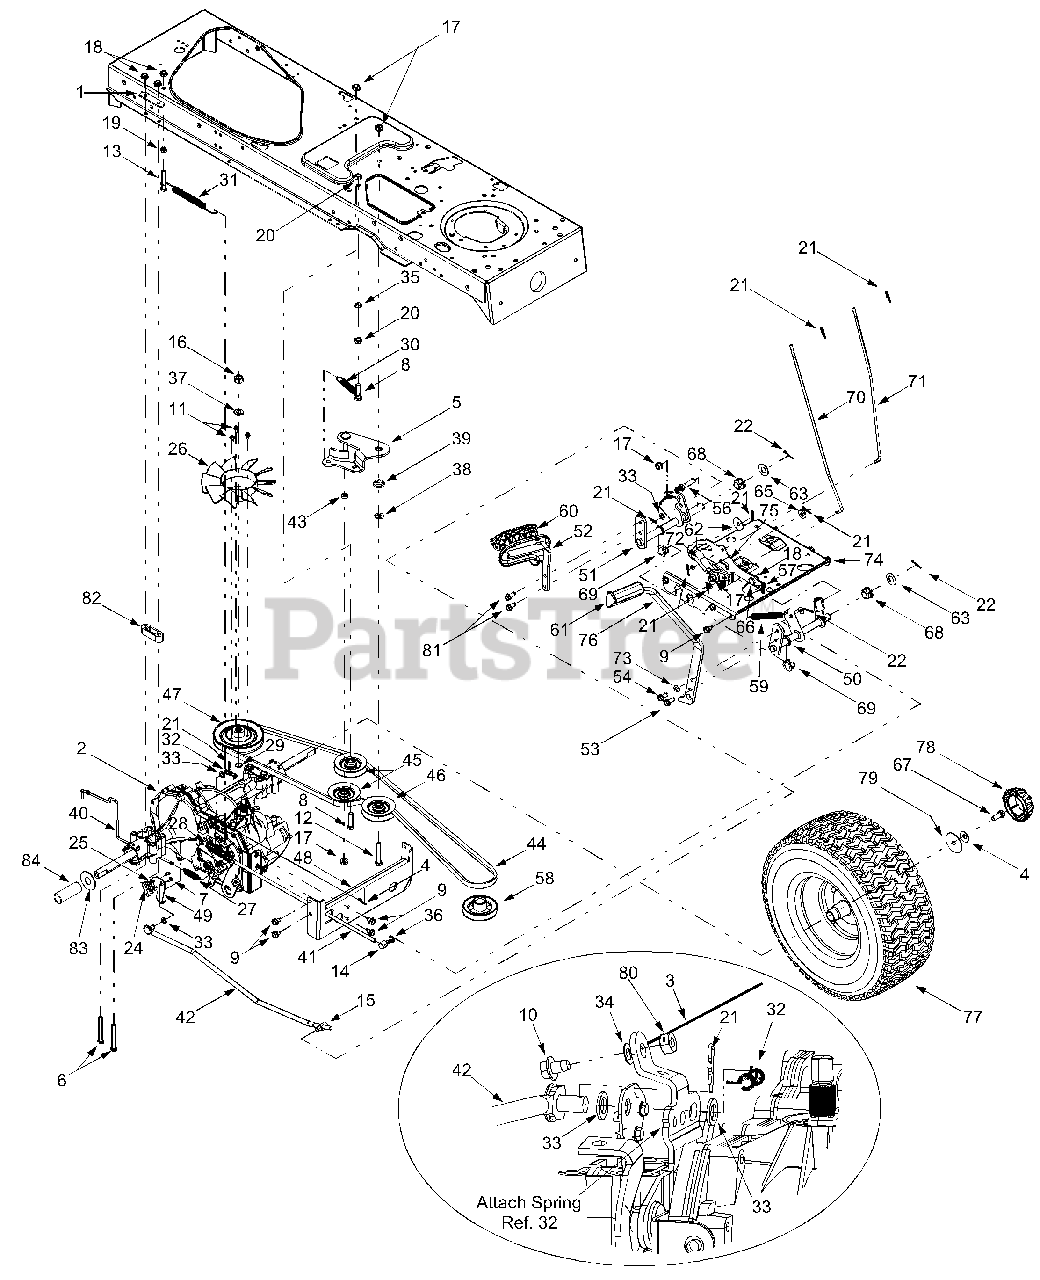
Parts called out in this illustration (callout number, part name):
2	Hydrostatic Transmission
3	Reverse Wire Harness Adapter & Ground
4	Bell Washer,.34 x.872
6	Hex Cap Screw, 5/16-18 x 2.75
7	Screw, #8-18 x.5
8	Hex Cap Screw, 3/8-16 x 1.5
9	Self-tapping Screw, 5/16-18 x.625
10	Self-tapping Screw, 1/4-20 x.375
11	Screw, #12-24 x.375
12	Hex Cap Screw, 3/8-16 x 2.25
13	Hex Cap Screw, 5/16-18 x 2.0
14	Ferrule, 5/16-18
15	Ferrule, 3/8-24
16	Hex Nut, 1/2-20
17	Flange Lock Nut, 3/8-16
18	Flange Lock Nut, 5/16-18
19	Hex Nut, 5/16-18
20	Hex Nut, 3/8-16
21	Internal Cotter Pin
22	Cotter Pin
24	Short Spring Switch
25	Insulator Nut Plate
26	10-inch Fan
27	Extension Spring,.48 x 2.03
28	Extension Spring,.59 x 4.0
29	Wire Ring
30	Extension Spring,.5 x 3.97
31	Extension Spring,.5 x 7.0
32	Extension Spring, 3/8 x 1.44
33	Flat Washer,.385 x.62 x.063
34	Flat Washer,.281 x.50 x.063
35	Lock Washer, 3/8
36	Flat Washer,.344 x.688 x.065
37	Lock Washer, 1/2
38	Flat Washer,.407 x.812 x.135
39	Shoulder Spacer,.38
40	Hydrostatic Bypass Rod
41	Hydrostatic Brake Rod
42	Hydrostatic Control Rod
43	Spacer,.376 x.625 x.22
44	Drive Belt
45	V-idler Pulley, 3.06
46	Flat Idler Pulley, 2.75
47	Input Pulley, 5.0
50	Brake Control Assembly
53	Self-tapping Screw, 5/16-18 x.875
54	Self-tapping Screw, 5/16-18 x.75
56	Pin, 3/8-16 x 2.43
57	Compression Spring,.405 OD x 1.17
58	Engine Pulley
59	Extension Spring,.50 OD x 6.37
60	Drive Pedal Pad
61	Brake Pedal Pad
62	Flat Washer,.411 x 1.25 x 1.0
63	Flat Washer,.64 x 1.24 x.06
65	Flat Washer,.406 x.875 x.105
66	Shoulder Screw,.437 x 1.62
67	Hex Cap Screw, 5/16-24 x.75
68	Hex Flange Bearing
69	Split Hex Flange Bearing
70	Cruise Control Rod
71	Brake Lock Control Rod
72	Cruise Latch
73	Flat Washer,.344 x.750 x.120
75	Drive Lockout Bracket
78	Deluxe Hub Cap
79	Flat Washer,.350 x 1.59 x.062
80	Hex Lock Nut, 1/4-20
81	Screw, 5/16-18 x.750
82	Axle Spacer
83	Flat Washer, .755 x 1.92 x .060
84	Axle Sleeve
